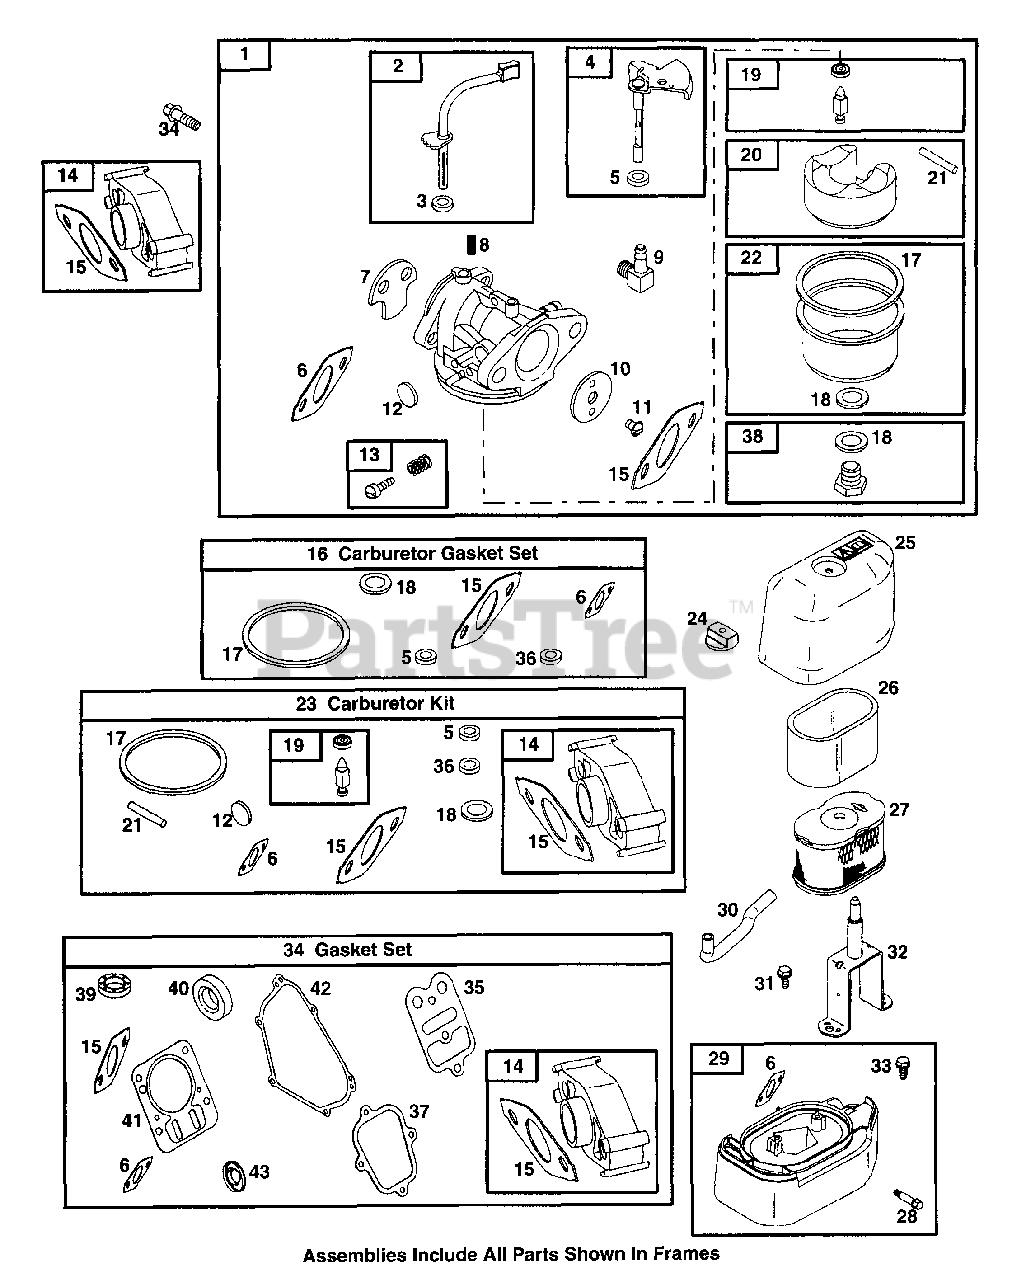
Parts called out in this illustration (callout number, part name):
1	Carburetor
2	Choke Shaft
3	Washer (Choke Shaft)
4	Throttle Shaft
5	Washer (Throttle Shaft)
6	Air Cleaner Gasket
7	Choke Valve
8	Detent Spring (Choke)
9	Hose Connector
10	Throttle Valve
11	Screw (Throttle Valve)
12	Welch Plug
13	Idle Speed Kit
14	Carburetor Spacer
15	Intake Gasket
16	Carburetor Gasket Set
17	Float Bowl Gasket
18	Sealing Washer
19	Needle Valve
20	Carburetor Float
21	Float Hinge Pin
22	Float Bowl
23	Carburetor Overhaul Kit
24	Air Cleaner Knob
25	Air Cleaner Cover
26	Pre-Cleaner Filter
27	Air Cleaner Cartridge Filter
28	Screw (Air Cleaner Base)
29	Air Cleaner Base
30	Breather Tube
31	Screw (Air Cleaner Bracket)
32	Air Cleaner Bracket
33	Screw (Air Cleaner Base)
34	Screw (Carburetor)
35	Cylinder Head Plate Gasket
36	Washer (Choke Shaft)
37	Rocker Cover Gasket
39	Oil Seal
41	Cylinder Head Gasket
42	Crankcase Gasket
43	Valve Seal
